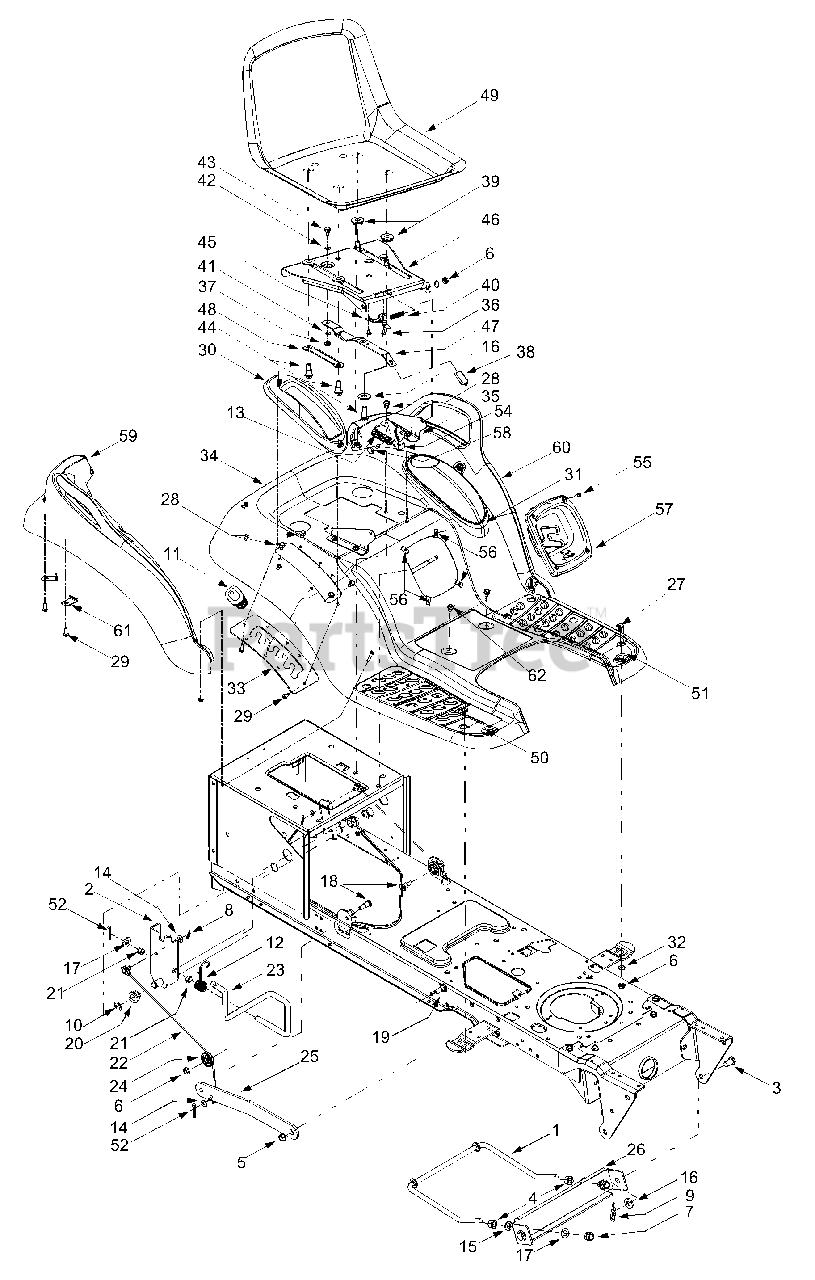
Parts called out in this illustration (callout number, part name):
1	Deck Stabilizer Rod (Model T809H)
3	Clevis Pin, .5 x .78
4	Hex Nut, 1/2-13
5	Flange Lock Nut, 3/8-16
6	Lock Nut, 5/16-18
7	Hex Nut, 1/2-13
8	Internal Cotter Pin
9	Internal Cotter Pin
11	Handle Grip
12	Torsion Spring
13	Extension Spring, .84 x 4.6
14	Flat Washer, 5/16
15	Lock Washer, 1/2
16	Flat Washer, .31 x 1.062 x .134
17	Flat Washer, .51 x 1.12 x .06
18	Hex Cap Screw, 5/16-18 x .62
19	Shoulder Screw, 3/8-16
20	Hex Flange Bearing
21	Snap Flange Bearing
22	Lift Cable, 16.16
23	Lift Handle
24	Roller Pulley
27	Carriage Bolt, 5/16 x .62
28	AB Screw, 5/16-12 x .75
29	Self-tapping Screw, 1/4-15 x .75
30	Lift Lever Cover
31	Cover w/ Cup Holder
32	Flat Washer, .349 x 1.0 x .063
36	Screw, #10-16 x .375
37	Hex Flange Lock Nut, 1/4-20
38	Seat Adjuster Grip
40	Compression Spring, .41 x 1.5
41	Spring Washer, .265 x .562 x .025
42	Flat Washer, .344 x .62 x .03
43	Shoulder Screw, .340 x .285,1/4-20
44	Shoulder Screw, .50 x .50, 3/8-16
45	Seat Stop
48	Seat Adjustment Selector
49	High Back Seat, Black
50	RH Foot Pad
51	LH Foot Pad
52	Cotter Pin
54	Seat Lift Bracket
55	Phillips Pan Screw, 1/4-20 x .75
56	U-type Speed Nut, 1/4-20
57	Shift Lever Cover
58	Shoulder Screw, .437 x .286
59	RH Fender Flare
60	LH Fender Flare
61	Fender Clips
62	TT Screw 1/4-20 x 0.5
